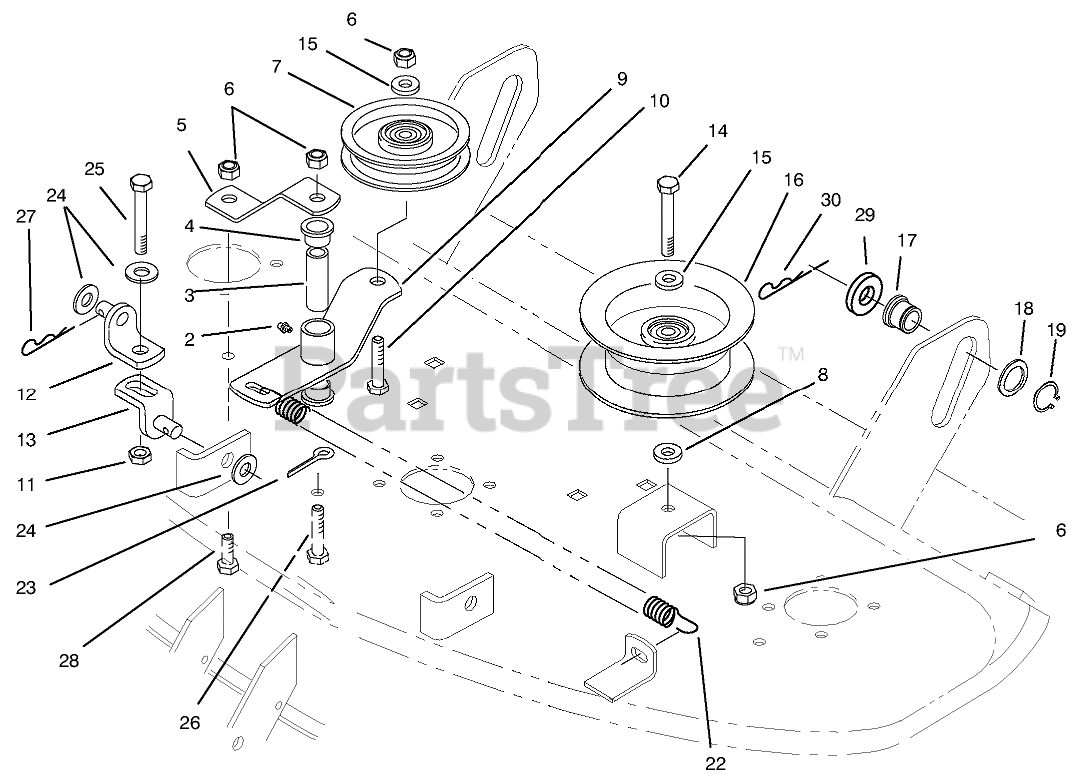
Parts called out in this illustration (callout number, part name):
2	FITTING-GREASE
3	SPACER
4	BUSHING
5	STRAP-BRACE
6	NUT-LOCK, NI
7	PULLEY-IDLER, FLAT
8	WASHER
9	Arm
10	SCREW-HH
11	NUT-JAM
12	BRACKET-LIFT, UPPER
13	BRACKET-LIFT, LOWER
14	SCREW-HH
15	WASHER-FLAT
16	PULLEY-IDLER
17	ROLLER-LIFT
18	Washer
19	RING-RETAINING
22	SPRING - EXTENSION
23	PIN-COTTER
24	WASHER-FLAT
25	SCREW-HH
26	SCREW-HH
27	Hairpin
28	SCREW-HH
29	WASHER-FLAT
30	Pin-Cotter
